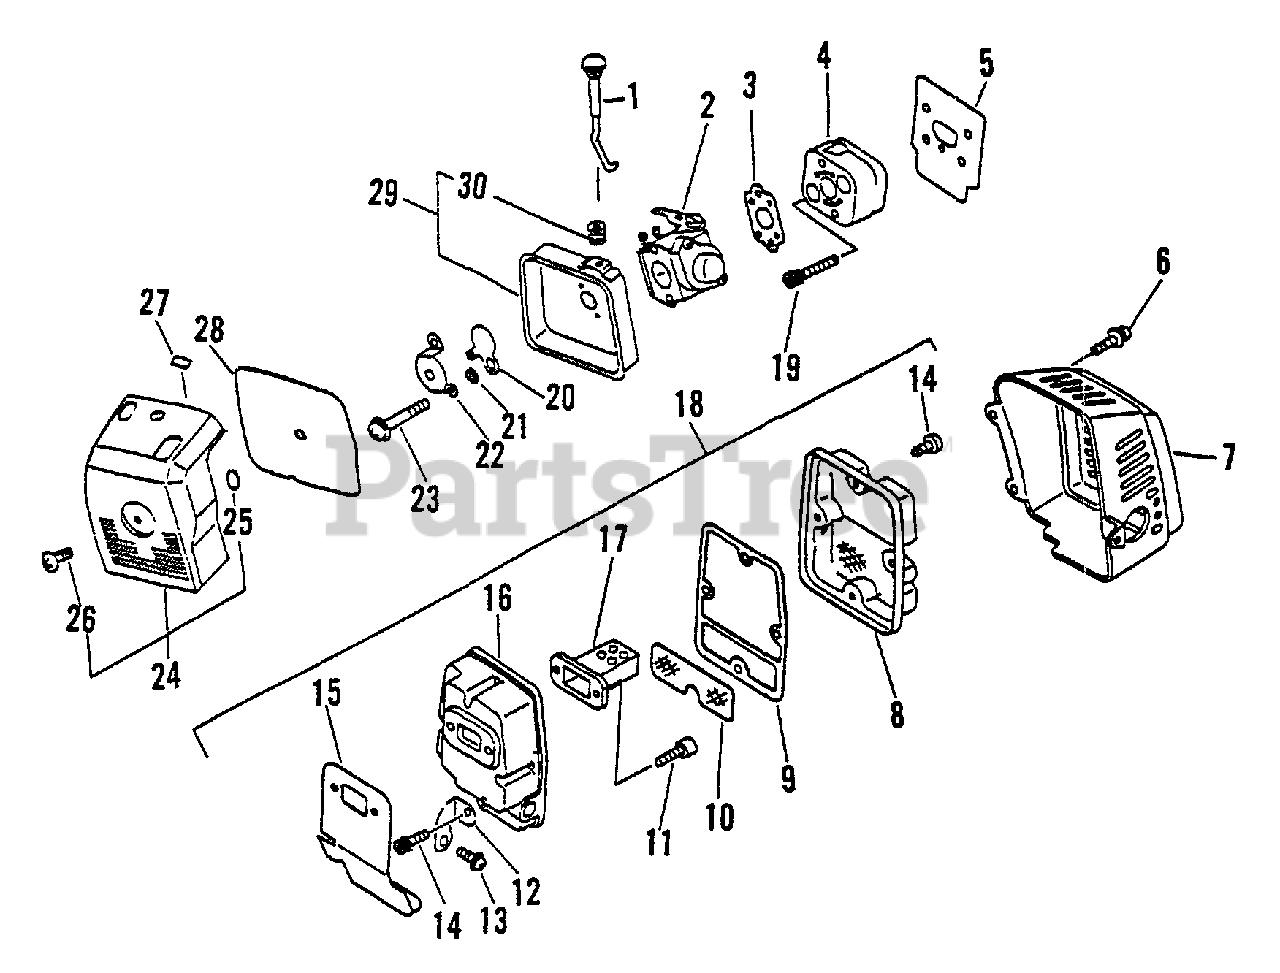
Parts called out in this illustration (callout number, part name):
1	ROD, CHOKE
2	CARBURETOR - C1U-K21
3	GASKET, INTAKE
4	INSULATOR, INTAKE
5	GASKET, INTAKE
6	SCREW 4×8
7	COVER, MUFFLER
8	COVER, MUFFLER
9	GASKET, EXHAUST
10	SCREEN, SPARK ARRESTER
11	BOLT M5×18
12	BRACKET, MUFFLER
13	SCREW 5×10
14	BOLT 5×14
15	GASKET, MUFFLER
16	MUFFLER
17	SILENCER
18	MUFFLER ASSY
19	BOLT 5×25
20	SHUTTER, CHOKE
21	WASHER 5.2×8×0.8T
22	PLATE, PREVENT
23	SCREW 5×45
24	AIR FILTER COVER ASSY
25	O-RING 3
26	THUMBSCREW
27	LABEL - CHOKE
28	FILTER, AIR
28	FILTER, HEAVY-DUTY AIR
29	CASE, AIR FILTER
30	GROMMET, CHOKE
